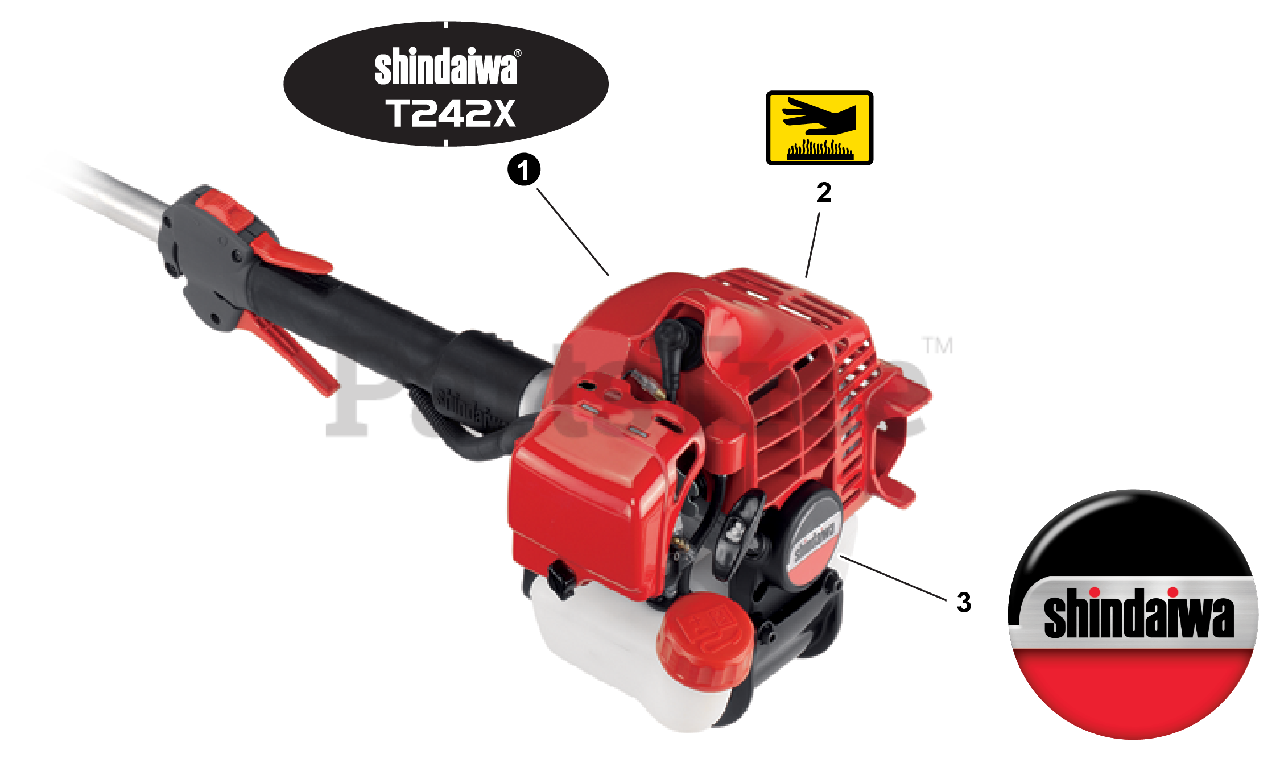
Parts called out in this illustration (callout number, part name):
1	LABEL, MODEL - T242X
2	LABEL, CAUTION - HOT
3	LABEL, RECOIL STARTER
